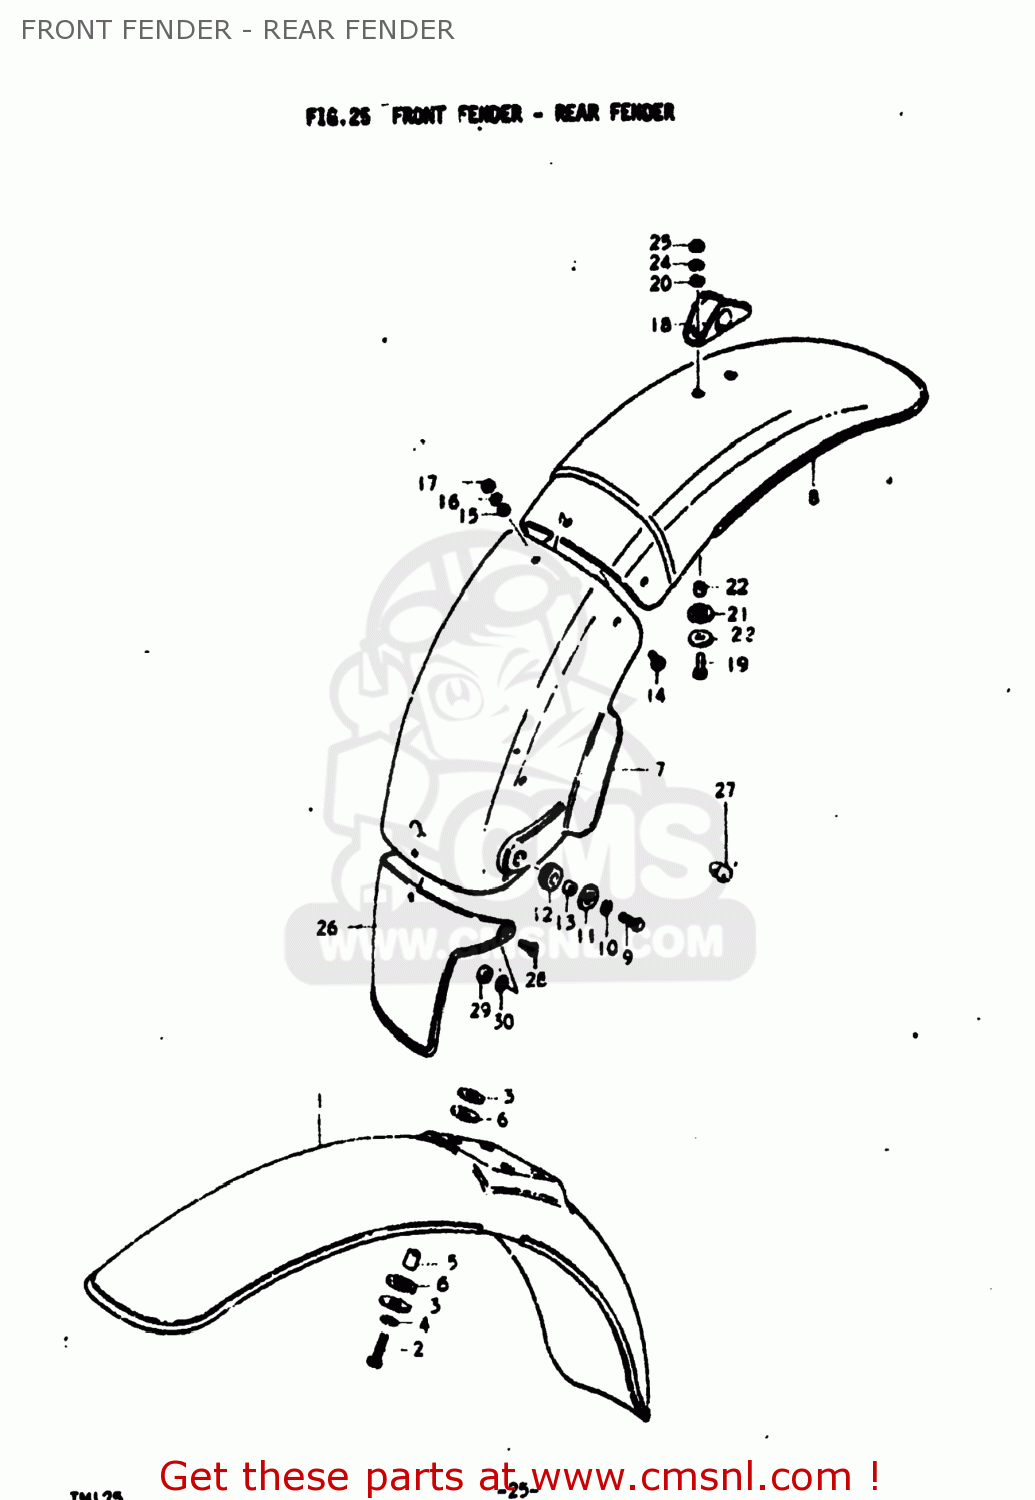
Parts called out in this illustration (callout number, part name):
1	FENDER,FRONT
2	BOLT
3	WASHER (6.5X24X1.2)
4	LOCK WASHER
5	SPACER (6.5X10.5X13.5)
6	CUSHION
7	FENDER,REAR
8	FENDER,REAR
9	BOLT
10	LOCK WASHER
11	WASHER (6.5X20X1.2)
12	CUSHION
13	SPACER(6.1X9X7.5)
14	SCREW
15	WASHER 5MM
16	LOCK WASHER
17	NUT
18	REINFORCEMENT,REAR FENDER
19	BOLT(6X18)
20	WASHER
21	CUSHION
22	SPACER
23	WASHER (6.5X20X1.2)
24	LOCK WASHER
25	NUT
26	MUD GUARD,REAR FENDER
27	CUSHION
28	SCREW
29	NUT
30	WASHER
